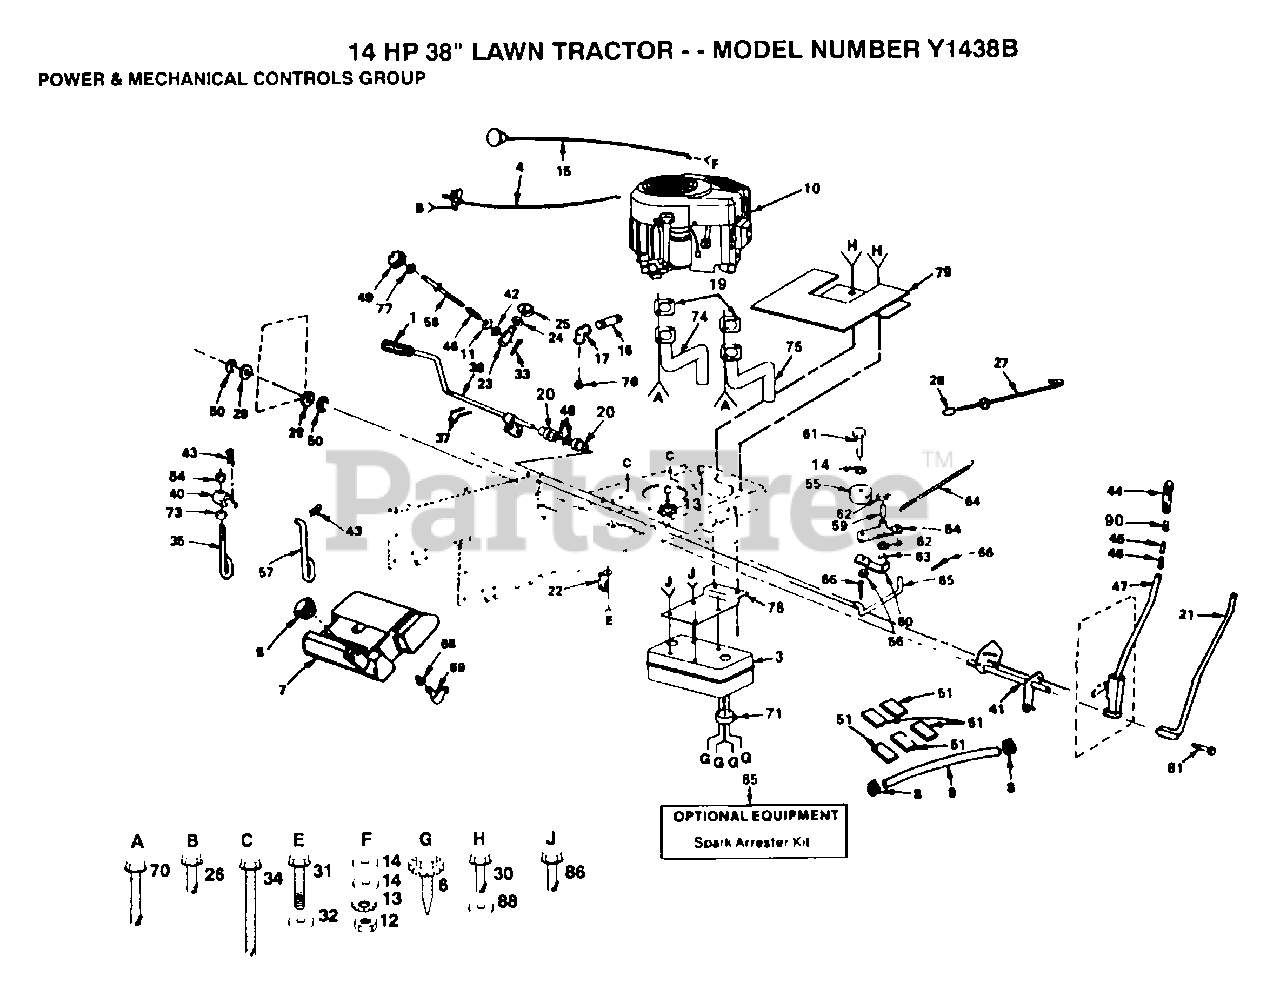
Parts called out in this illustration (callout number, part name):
1	PEDAL COVER T
8	HOSE CLAMP
9	HOSE T
10	PIPE, EXHAUST
11	WASHER
13	LOCKWASHER
14	WASHER
16	PIPE NIPPLE LT
17	ELBOW
20	NYLON BEARING
21	LEVER ROD LT
23	TRUNION LT
24	WASHER
25	KLIP RING
26	SCREW LT
27	ROD BRAKE PARK
28	PLUNGER CAP T
29	WASHER
30	SCREW
31	SCREW
32	WASHER
34	SCREW LT
35	PIVOT PIN T
41	SHAFT LIFT LT
42	NUT T
44	GRIP
46	SPRING T
48	WASHER LT
49	HDLE ADJ LIFT
50	E-RING
51	PAD-SPACER LT
54	ARM IDLER
57	LIFT LINK LT
58	ROD LIFT LT
59	"LY, BEARING"
60	RETAIN BELT
62	WASHER LT
63	KLIP RING
64	"SPRING, RETURN LT"
65	"LINK, CLUTCH T"
66	COTTER PIN
68	BUSHING OUTLET T
69	FUEL TANK STEM GT
71	DEFLECTOR.222573
73	NUT
74	TUBE ASSY EXH LH
75	TUBE ASSY EXH RH
77	NUT
78	BRACKET MUFFLER
81	"BOLT,HEX"
86	SCREW ST
88	WASHER
